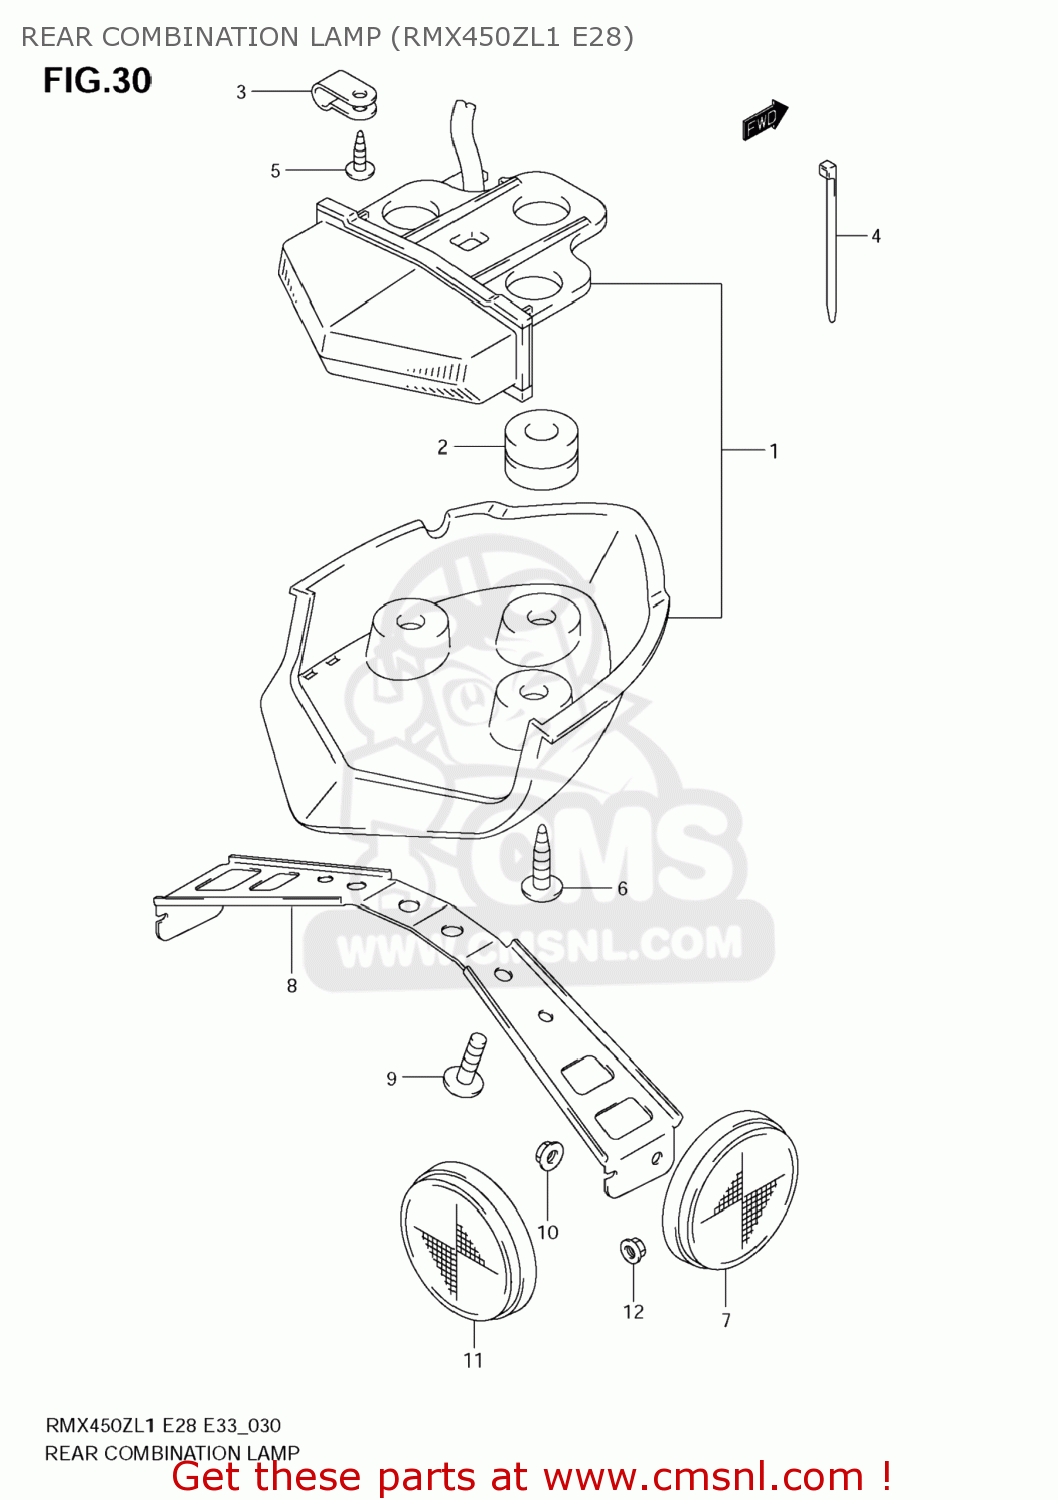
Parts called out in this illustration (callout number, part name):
1	LAMP ASSY, TAIL
2	CUSHION
3	CLAMP
4	CLAMP(L:145)
5	SCREW
6	SCREW
7	REFLECTOR ASSY,RR SIDE
8	BRACKET, REAR SIDE
9	SCREW
10	NUT
11	REFLECTOR ASSY,RR SIDE
12	NUT
